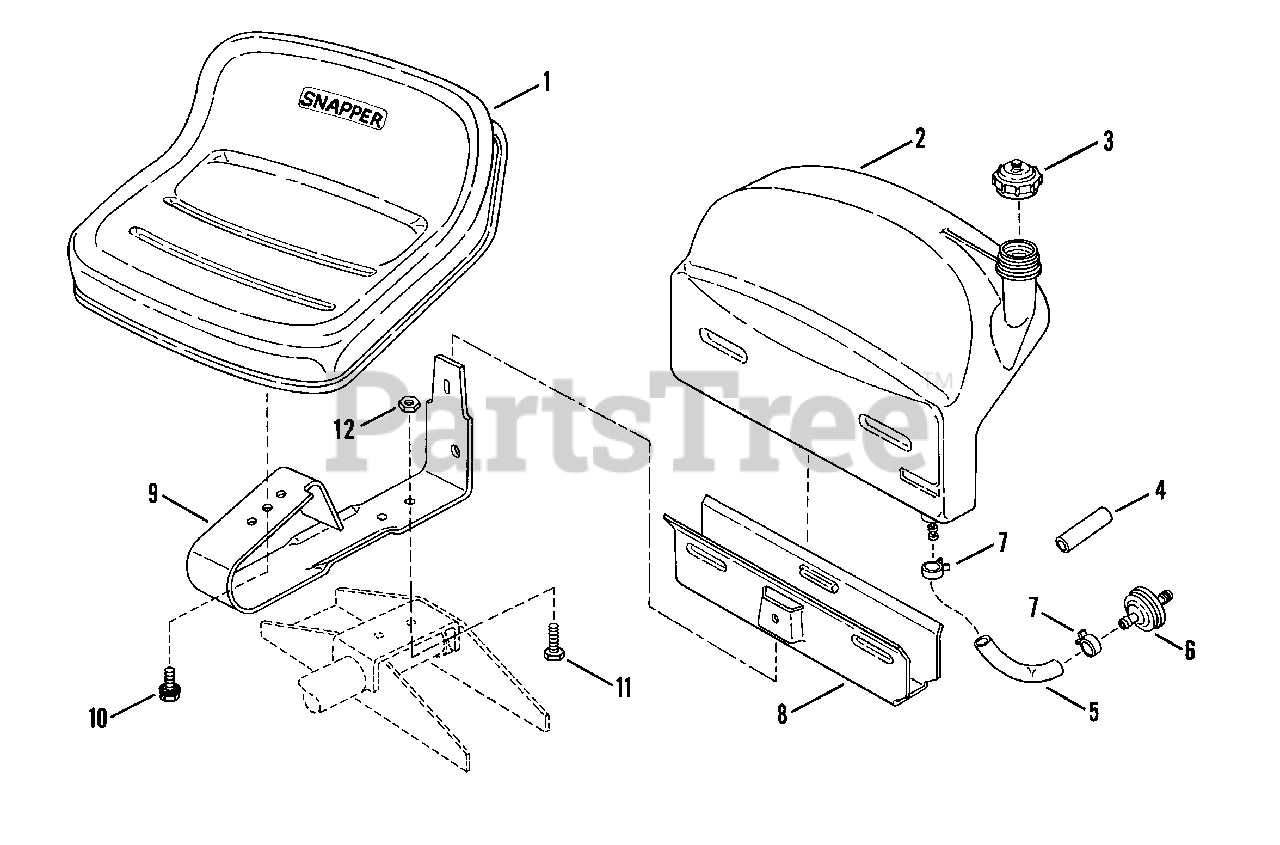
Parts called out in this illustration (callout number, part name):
1	SEAT, Operator
2	ASSEMBLY, Fuel Tank
3	CAP, Fuel Tank
4	HOSE, Fuel, 5" (Tecumseh)
5	HOSE, Fuel, 7" (Briggs & Stratton)
6	FILTER, Fuel, In-Line
7	CLAMP, Fuel Line
8	BRACKET, Fuel Tank
9	SPRING, Operator's Seat
10	BOLT, 1/2-13x3/4" Hex Flange Lock
11	BOLT, 3/8-16x1 Flange Lock
12	NUT, 3/8-16 Hexlock
